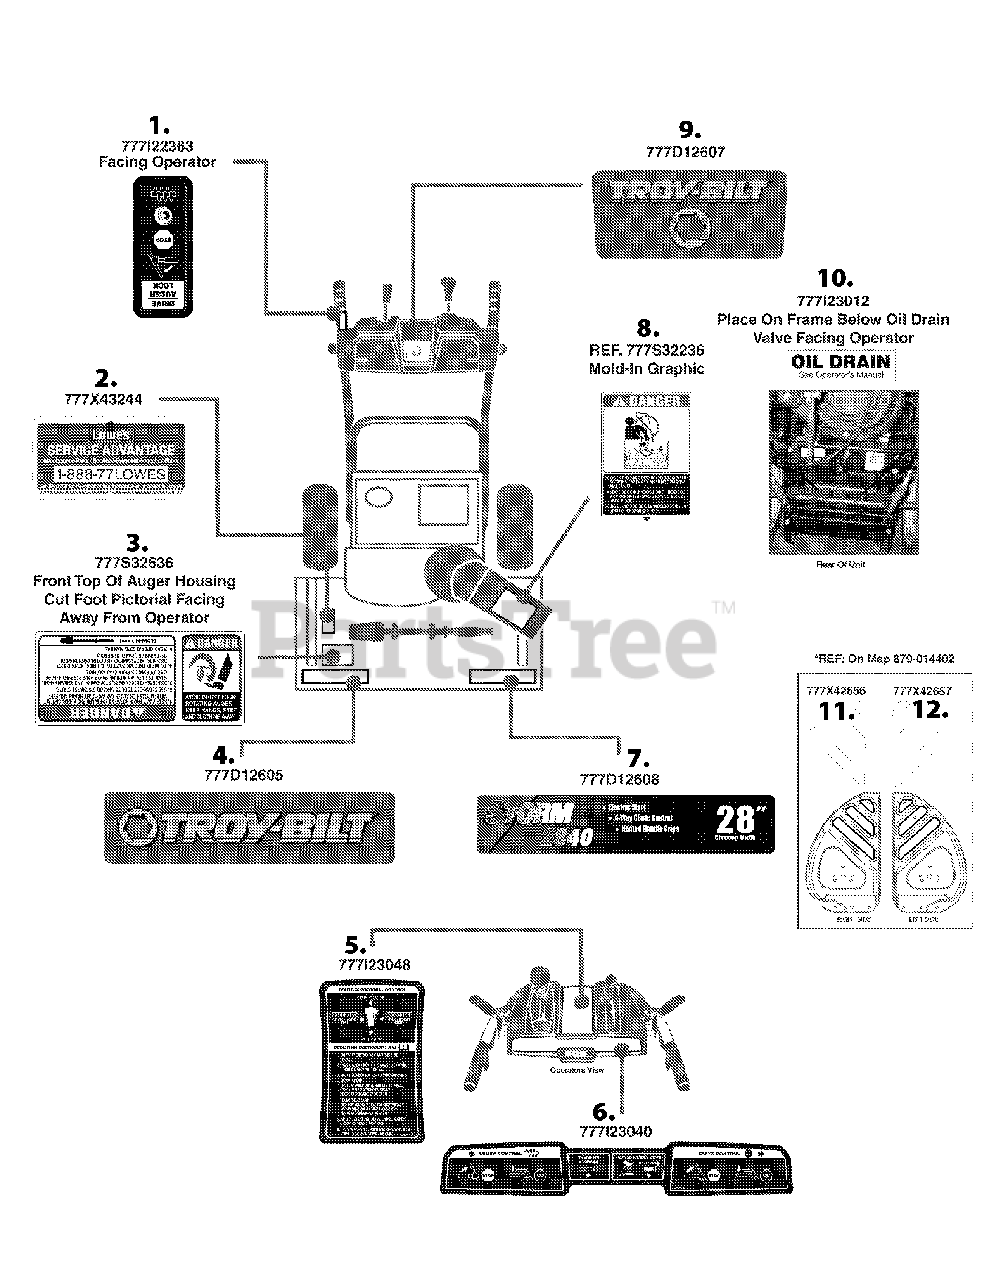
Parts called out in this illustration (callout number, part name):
1	LABEL-DRV/AUGR LOCK
2	LABEL-LOWES:SERVICELBL:77LOWES
3	LABEL-SNOW HOUSING
4	LABEL-SNOW FRONT LH AUGER TROY
5	LABEL-SNW:Q PNL:ST INSTR:B&S
6	LABEL-SNW:N/O PNL:TBILT W/HH
7	LABEL-SNOW FRONT RH AUGER STORM
8	LABEL-SNOW CHUTE
9	LABEL-SNOW HANDLE 4 STYLE FRONT
10	LABEL-SNOW OIL DRAIN
11	LABEL-SNOW RH AUGER REFLECTOR
12	LABEL-SNOW LH AUGER REFLECTOR
